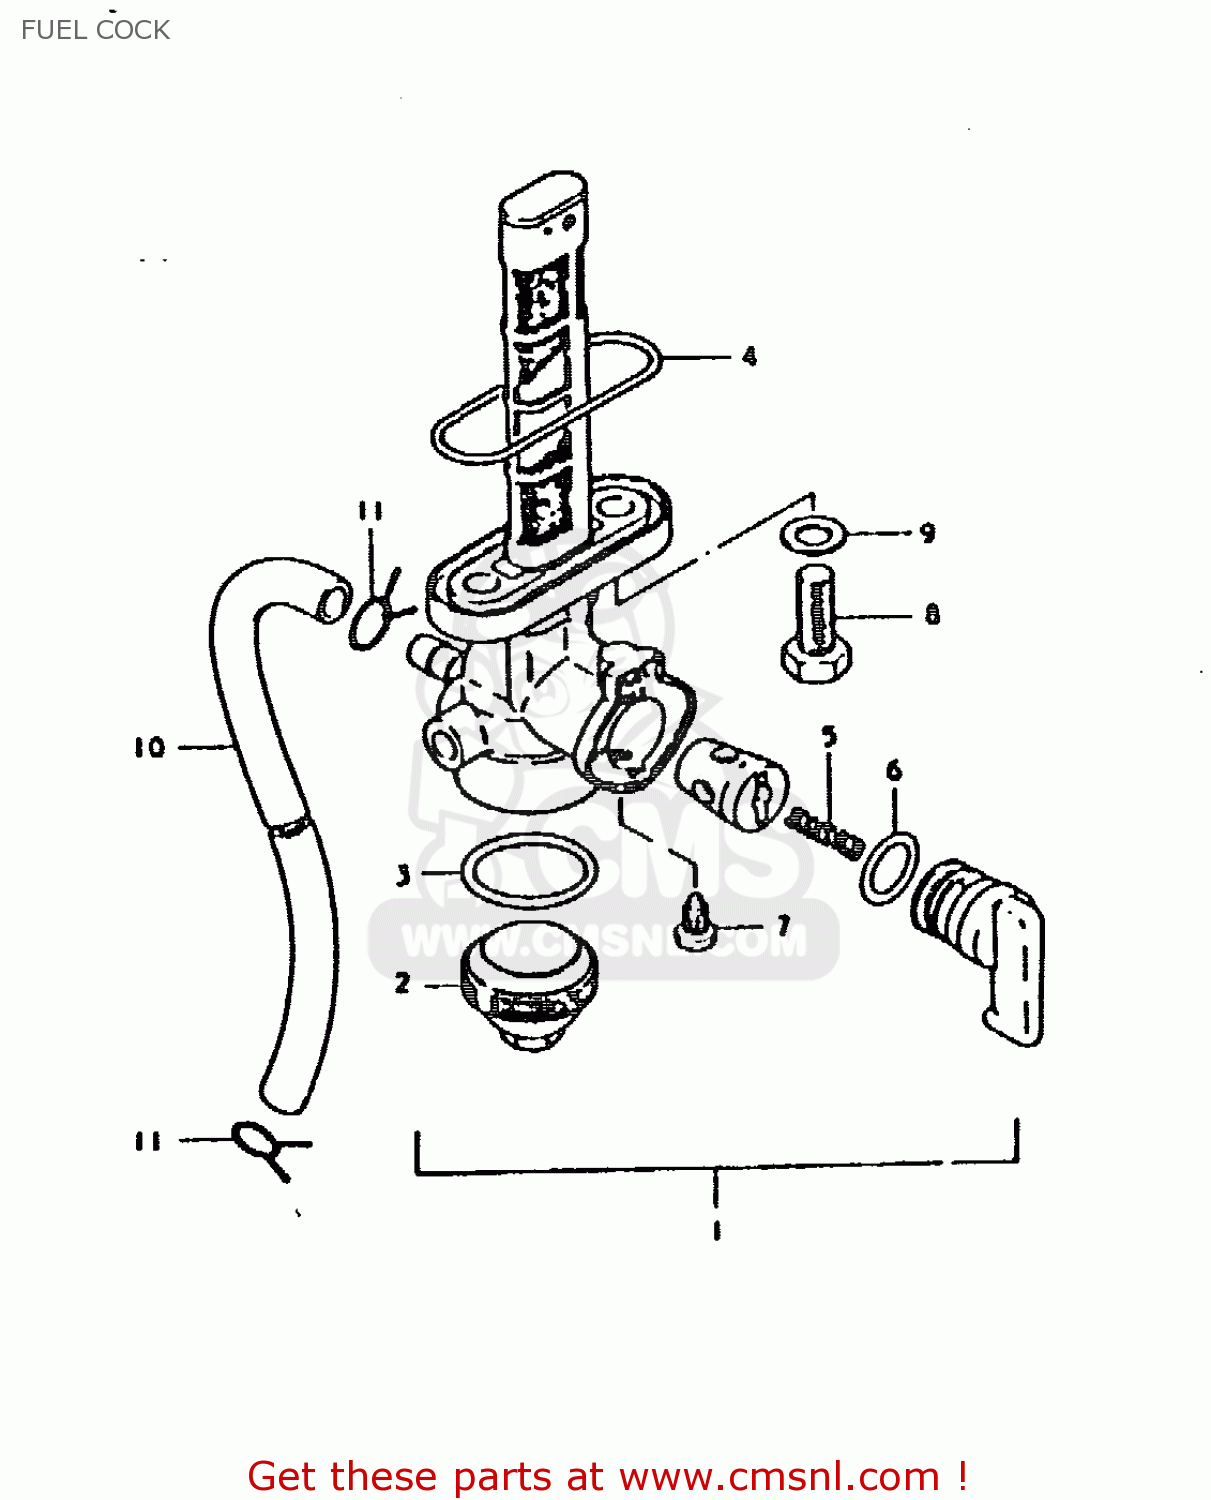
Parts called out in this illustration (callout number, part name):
1	COCK ASSEMBLY,FUEL
2	CUP,STRAINER
3	GASKET,FILTER (NAS)
4	O RING,FUEL COCK
5	SPRING
6	O-RING
7	SCREW
8	BOLT L:16
9	GASKET
10	HOSE
11	CLIP
